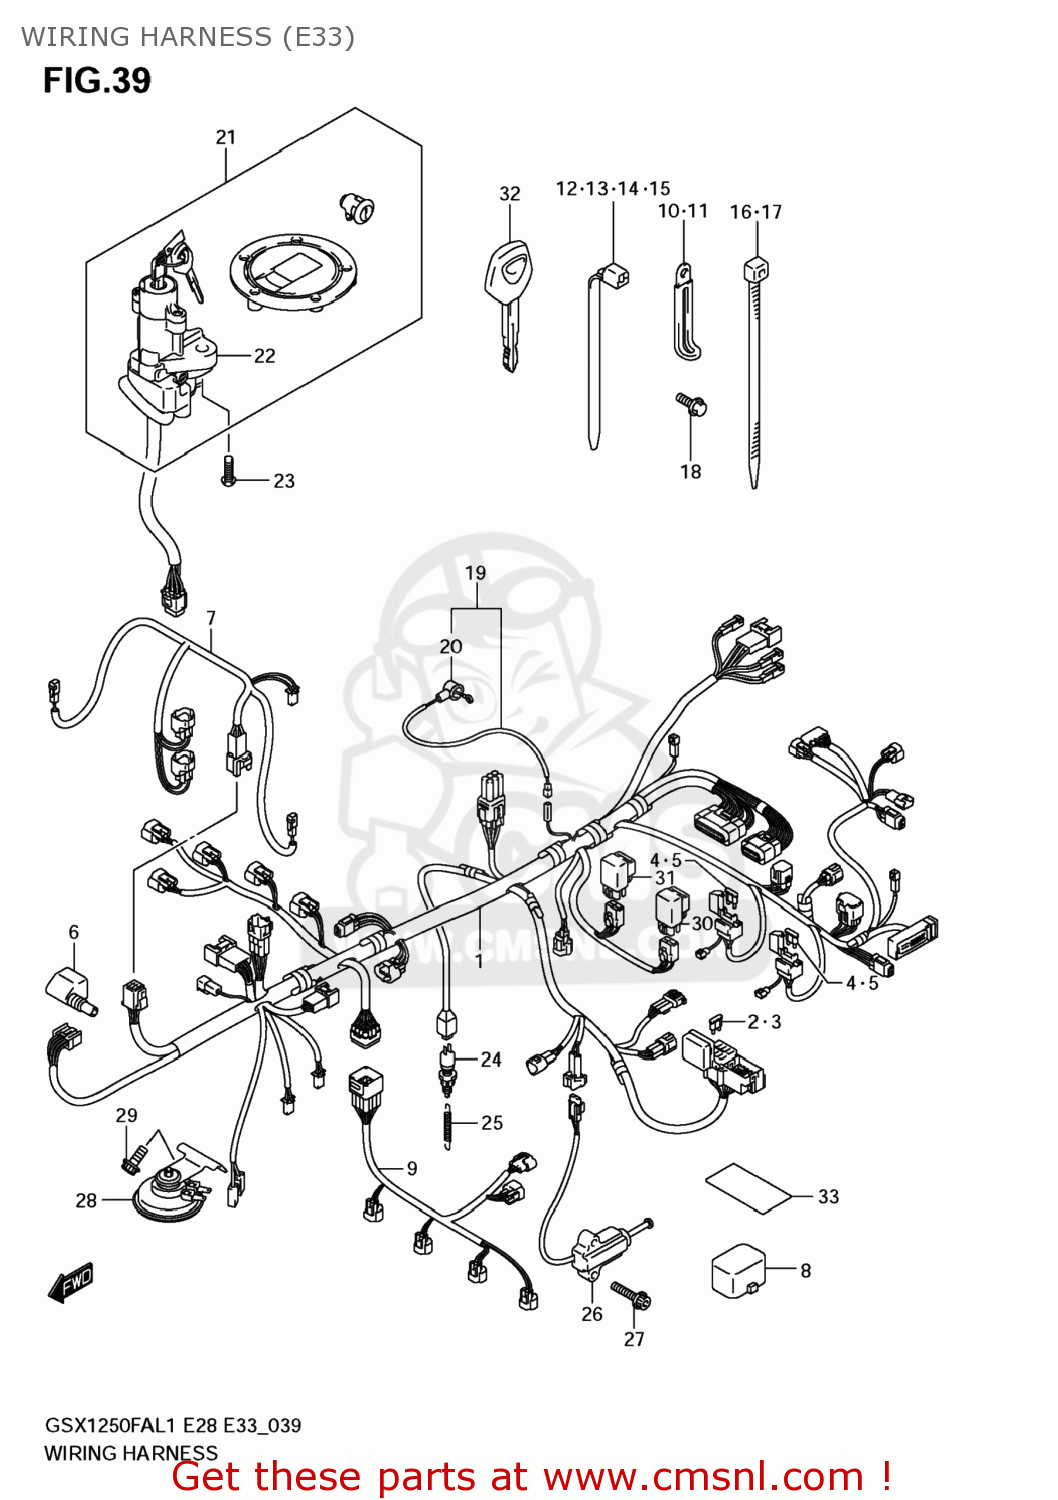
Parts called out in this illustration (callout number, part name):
1	HARNESS,WIRING NO.1
2	FUSE(10A)
3	FUSE(15A)
4	FUSE(15A)
5	FUSE(20A)
6	COVER,SPEEDOMETER COUPLER
7	HARNESS,WIRING NO.2
8	CAP,TS
9	WIRE,INJECTOR LEAD
10	CLAMP(L:45)
11	CLAMP(L:80)
12	CLAMP(L:95)
13	CLAMP(L:125)
14	CLAMP(L:165)
15	CLAMP(L:235)
16	CLAMP(L:145)
17	CLAMP(L:100)
18	BOLT
19	WIRE,OIL PRESSURE SWITCH LEAD
20	CAP,OIL PRESSURE SWITCH
21	LOCK SET
22	LOCK ASSY,STEERING
23	BOLT(8X20)
24	SWITCH ASSY,STOP LAMP
25	SPRING
26	SWITCH ASSY,SIDE STAND
27	BOLT
28	HORN ASSY
29	BOLT
30	RELAY ASSY
31	RELAY ASSY
32	KEY,BLANK
33	TAPE,RR FENDER
